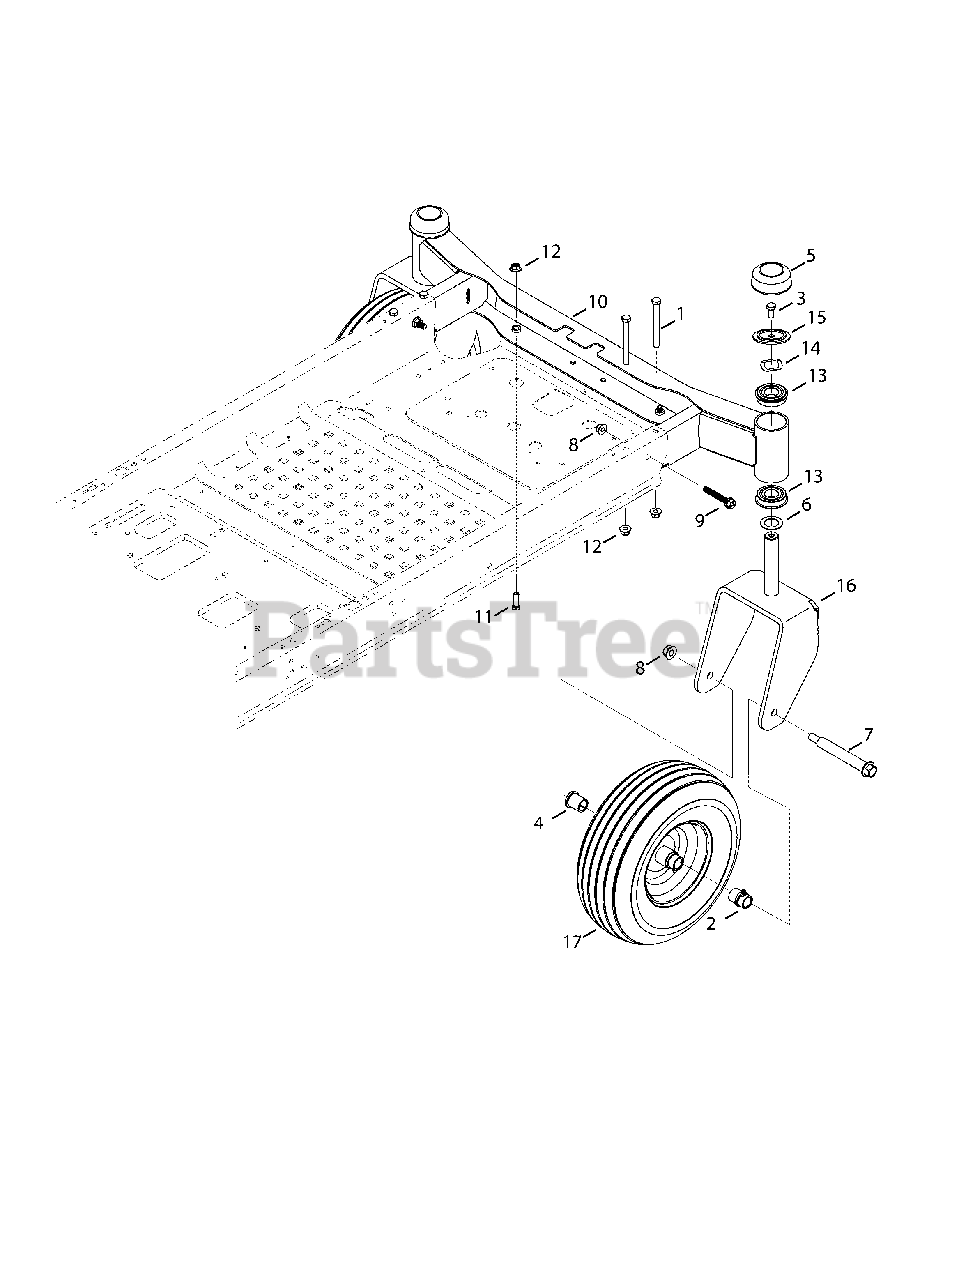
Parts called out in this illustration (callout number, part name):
1	SCREW, 3/8-16 X 3.75 GR5
2	BEARING, Flange W/Zerk Fitting
3	SCREW, 3/8-16 X .75 GR 5
4	BEARING, Flange
5	CAP, Caster Axle
6	WASHER, 1.010X1.560X.060
7	BOLT, 1.00X4.75X1/2-13, Shoulder
8	NUT, 1/2-13, Flange Lock
9	SCREW, 3/8-16 X 2.00 GR5
10	ASSEMBLY, Front Axle
11	SCREW, 3/8-16 X 1 GR5
12	NUT, Hex Flange, Nylock, 3/8-16
13	BEARING, Ball
14	WASHER, Wave
15	SPACER, Shoulder
16	YOKE, Caster Wheel
17	WHEEL, Caster
